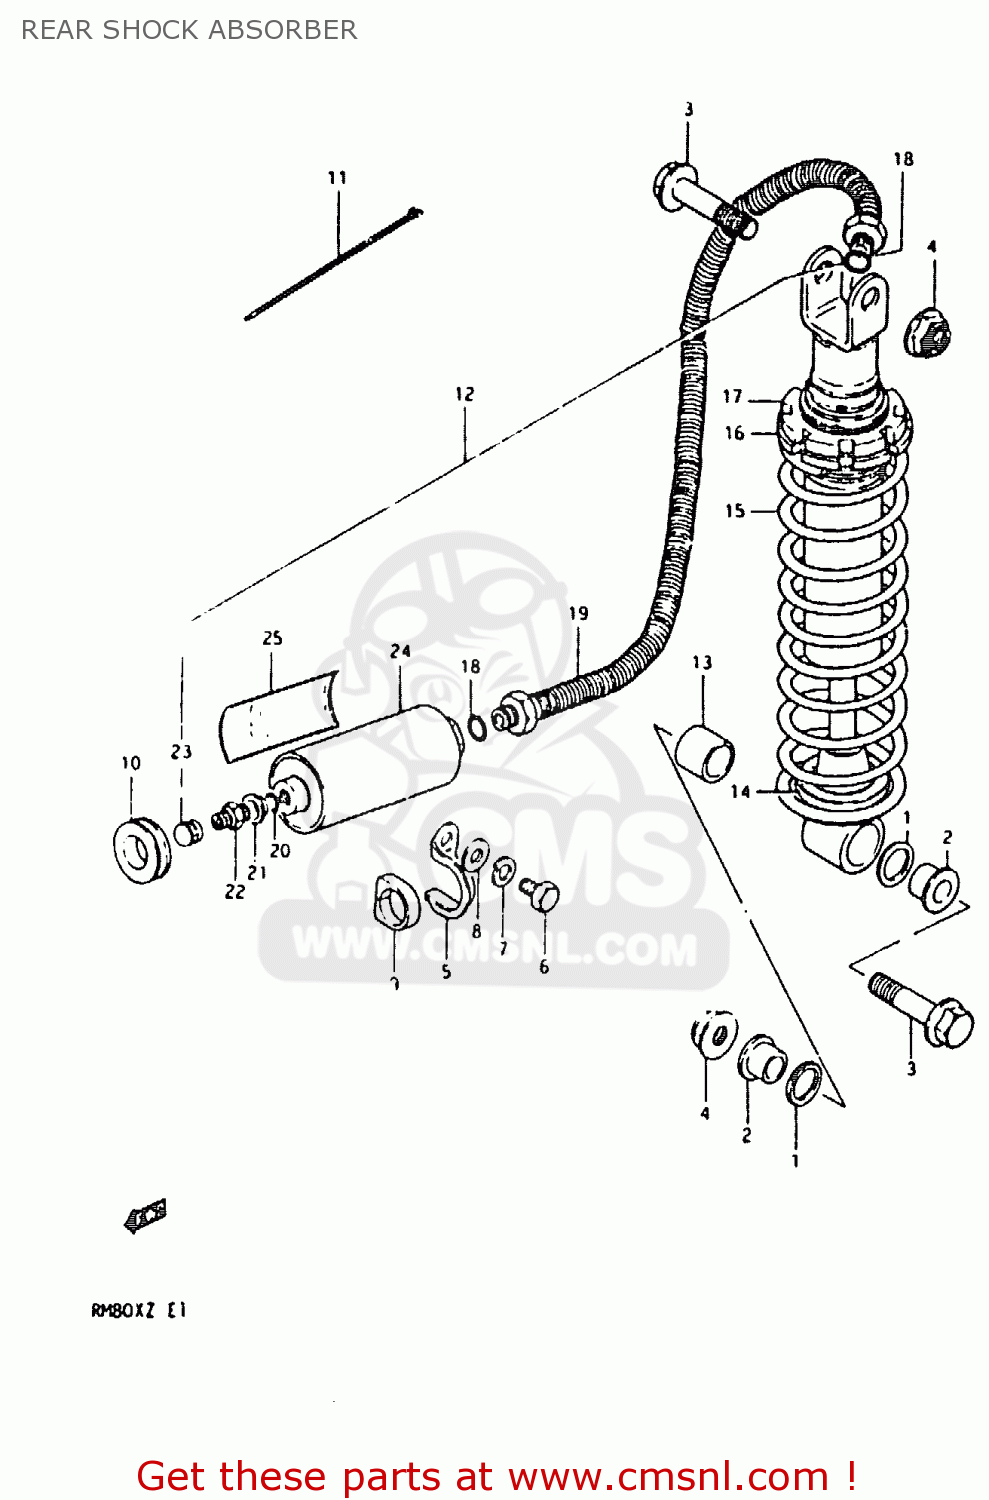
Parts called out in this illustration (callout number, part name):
1	DUST SEAL, LOWER
2	SPACER,LEVER CUSHION UNIT
3	BOLT(10X50)
4	NUT
5	BRACKET, RESERVER TANK
6	BOLT
7	LOCK WASHER
8	WASHER
9	CUSHION,REAR SHOCK ABSORBER TANK
10	CUSHION, FRONT
11	CLAMP
12	ABSORBER ASSEMBLY,REAR SHOCK
13	BUSH,LEVER CUSHION UNIT
14	SEAT, SPRING
15	SPRING
16	ADJUSTER,SPRING
17	NUT,SPRING ADJUSTER
18	O-RING
19	HOSE,REAR SHOCK ABSORBER
20	O-RING
21	WASHER
22	VALVE,FRONT FORK AIR
23	CAP,FRONT FORK AIR VALVE
24	RESERVE TANK,REAR SHOCK
25	LABEL
